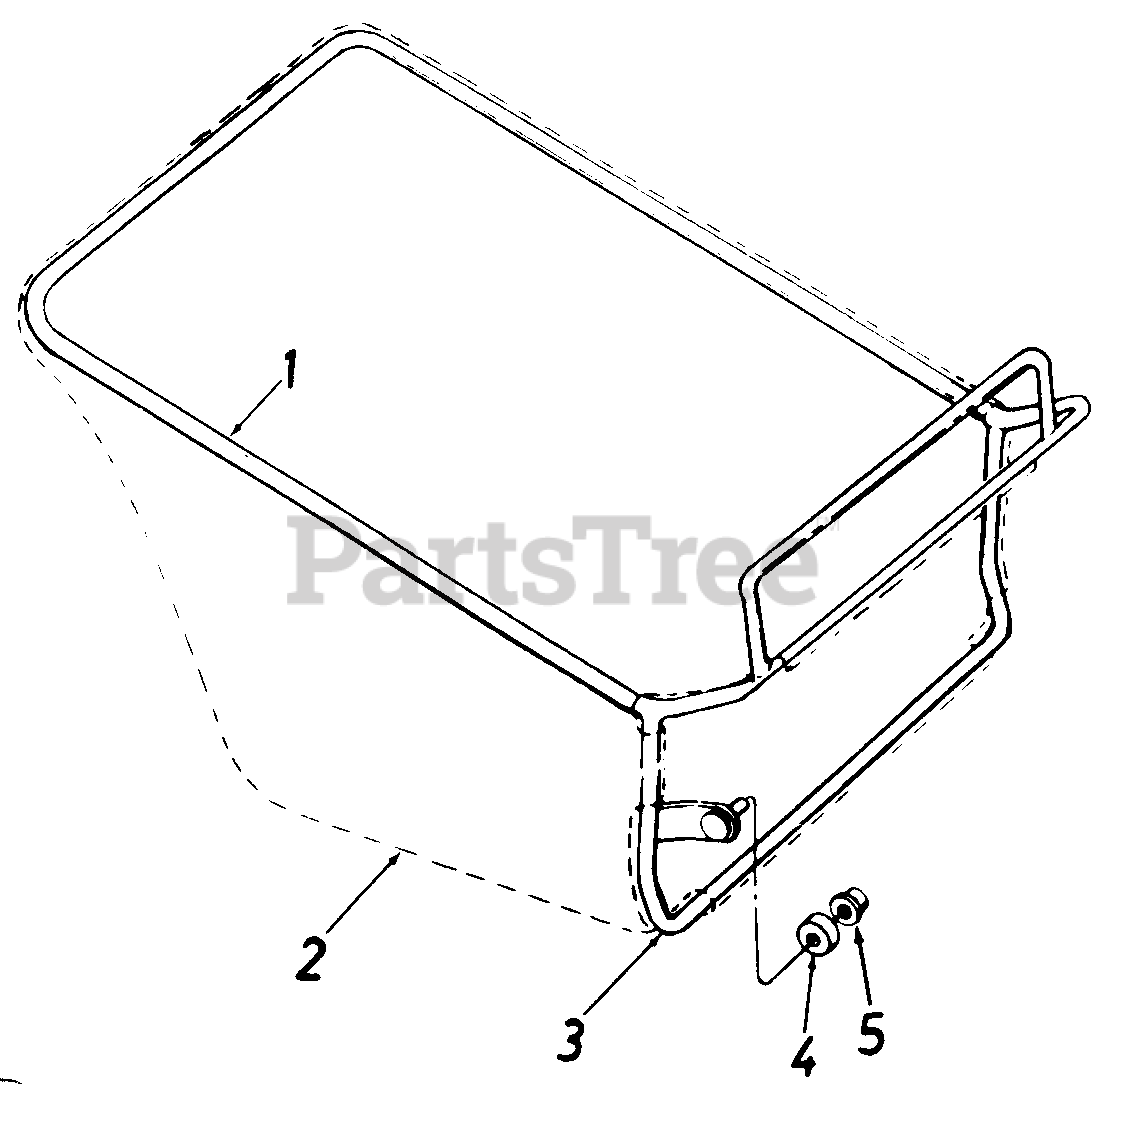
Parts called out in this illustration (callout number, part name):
1	Upper Frame
2	Grass Bag
5	Push Cap
